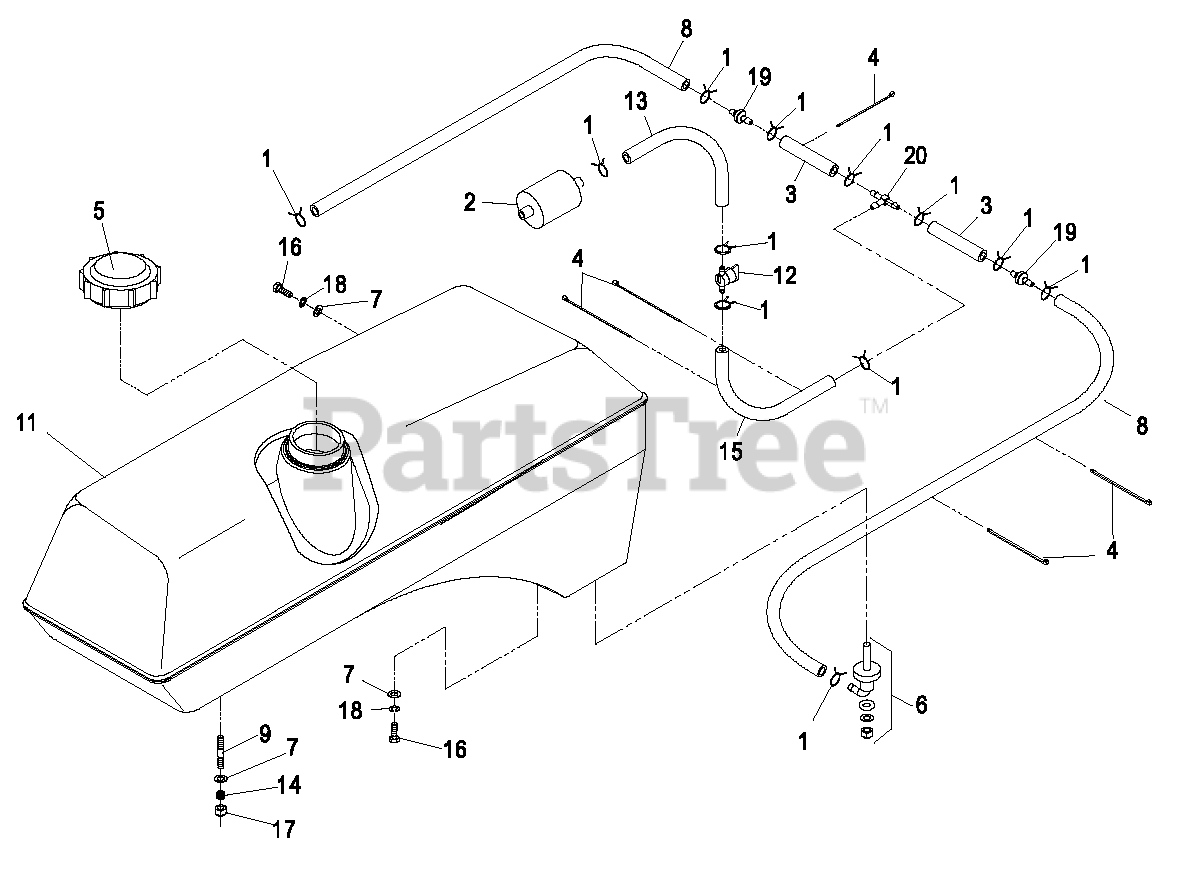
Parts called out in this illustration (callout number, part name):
2	Kohler Part No. 2405010 Fuel Filter
2	Kawasaki Part No. 49019-7001 Fuel Filter
3	Hose, Fuel Line 2 1/2"
4	TIE-PLASTIC
5	CAP-FUEL, GAS
6	FITTING-FUEL, BULKHEAD
6	O-RING,BULKHEAD FITTING
7	WASHER-PLAIN
8	HOSE-FUEL
9	STUD
12	VALVE-FUEL
13	HOSE-FUEL
14	SPRING-TANK, FUEL
15	HOSE-FUEL
16	SCREW-HH
17	NUT-LOCK, NI
18	WASHER-LOCK
19	VALVE-CHECK, FUEL
20	FITTING-TEE, BARBED
